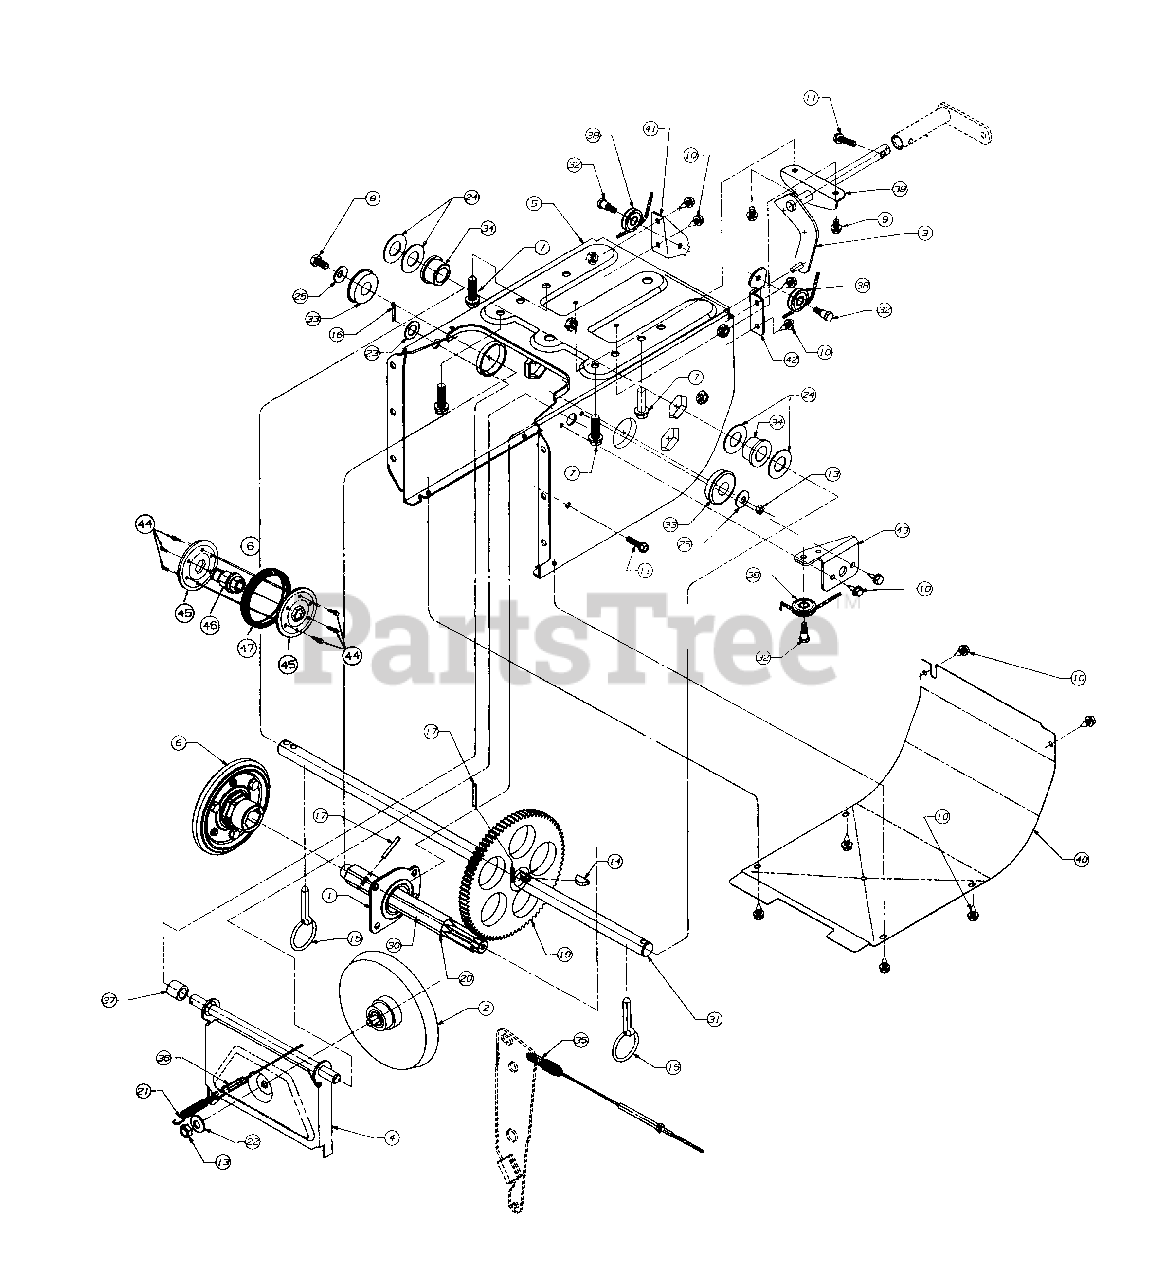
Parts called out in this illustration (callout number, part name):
1	Bearing Ass'y.
2	Ass'y., Friction Wheel Disc
3	Rod Shift, Wheel Drive
7	Hex Self-Tap Screw
8	Hex Screw 5/16 - 8
9	Scr., Hex Wash. Hd., TT 1/4-20 x .5"
10	Hex Self-Tap Scr.
11	Screw, Hex
13	Nut, Hex
15	Pin, Klick
16	Pin, Cotter
17	Pin, Roll
20	Shaft, Hex
21	Extension Spring
22	Washer, Bell
23	Flat Washer
24	Washer, Flat
25	Washer, Bell
30	Lubricant
32	Screw, Shoulder
33	Bearing, ball
34	Flange Bearing
35	Cable, Auger
36	Cable, Clutch
37	Spacer
38	Roller, Cable
45	Friction Plate
46	Friction Wheel Hub
47	Friction Wheel Rubber
